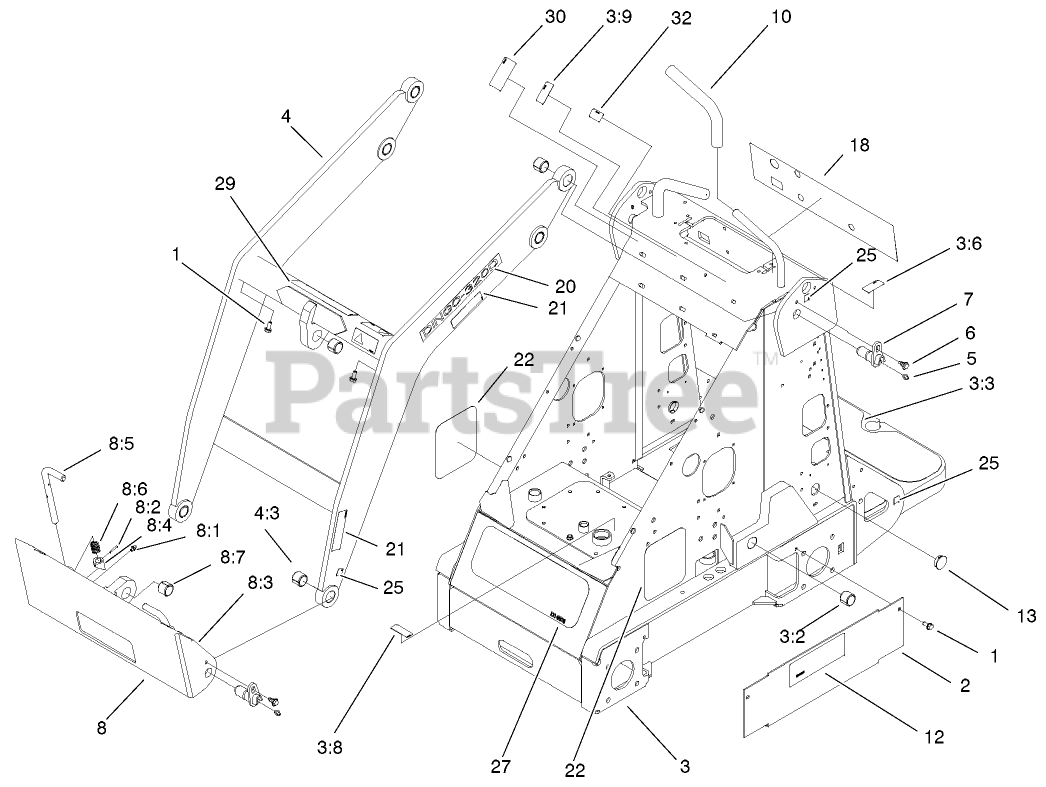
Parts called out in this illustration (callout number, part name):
1	SCREW-HWHTF
2	COVER-HOSE
3	FRAME ASM
3:2	BUSHING-TENSION
3:3	TREAD-FOOT
3:6	DECAL-THROTTLE
3:8	DECAL-OIL, HYD
3:9	DECAL-SELECTOR
4	LOADER ASM
4:2	SCREW-HWHTF
4:3	BUSHING-TENSION
5	FITTING-GREASE
6	BOLT-SHOULDER
7	PIN-PIVOT
8	QUICK ATTACH ASM
8:1	FITTING-GREASE
8:2	PIN-SPECIAL
8:3	MOUNT-ATTACH, QUICK
8:4	CAM-ATTACH, QUICK
8:6	SPRING-COMPRESSION
8:7	BUSHING-TENSION
10	GRIP-CUSHION
12	DECAL-4-PAW
13	PLUG-HOLE
18	DECAL-PANEL, CONTROL
20	DECAL-DINGO 320D
21	DECAL-PINCH
22	DECAL-DINGO, SIDE
25	DECAL-POINT, LIFT
27	DECAL-DINGO, FRONT
29	DECAL-CAUTION
30	DECAL-POWER, AUXILIARY
32	DECAL-LIMITER, SPEED
